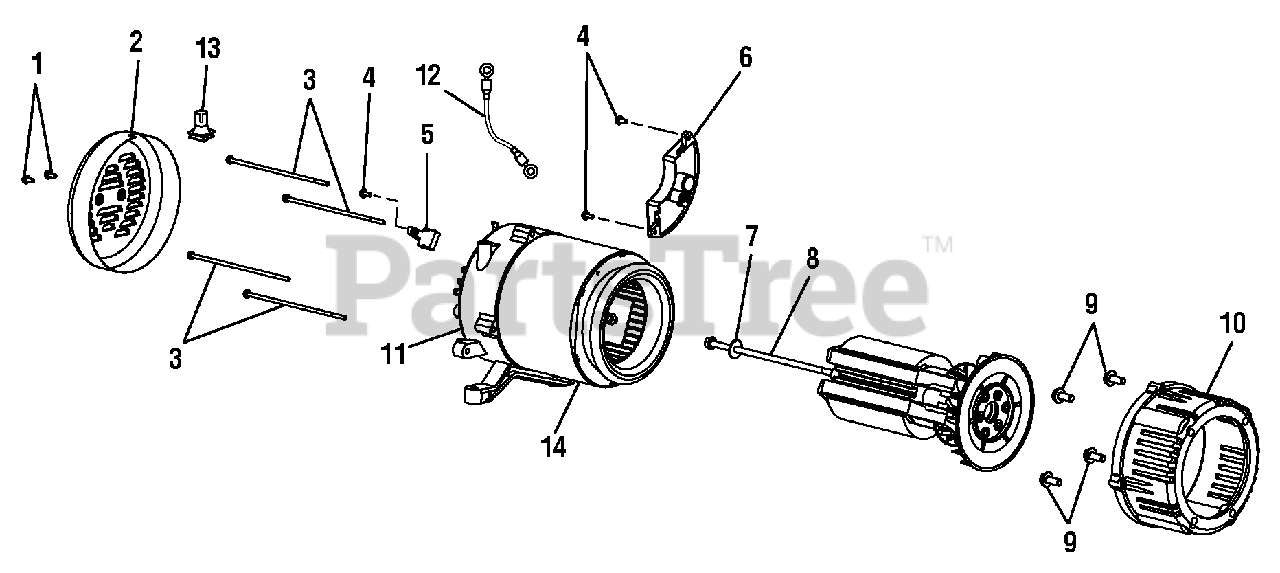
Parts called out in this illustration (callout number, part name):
1	Bolt (M5 x 10 mm, FlangeHex Hd.)
2	Brush Cover
3	Bolt (1/4-20 x 6 in., Hex Hd.)
4	Bolt (M5 x 16 mm, Flange Hex Hd.)
5	Brush Assembly
6	Automatic Voltage Regulator
7	Washer (5/16 in.)
8	Bolt (5/16-24 x 230 mm, Hex. Hd.)
9	Bolt (3/8-16 x 1-1/4 in.)
10	Engine Adapter
11	Bearing Support
12	Bonding Wire
13	Rubber Boot
14	Generator Head Cover
